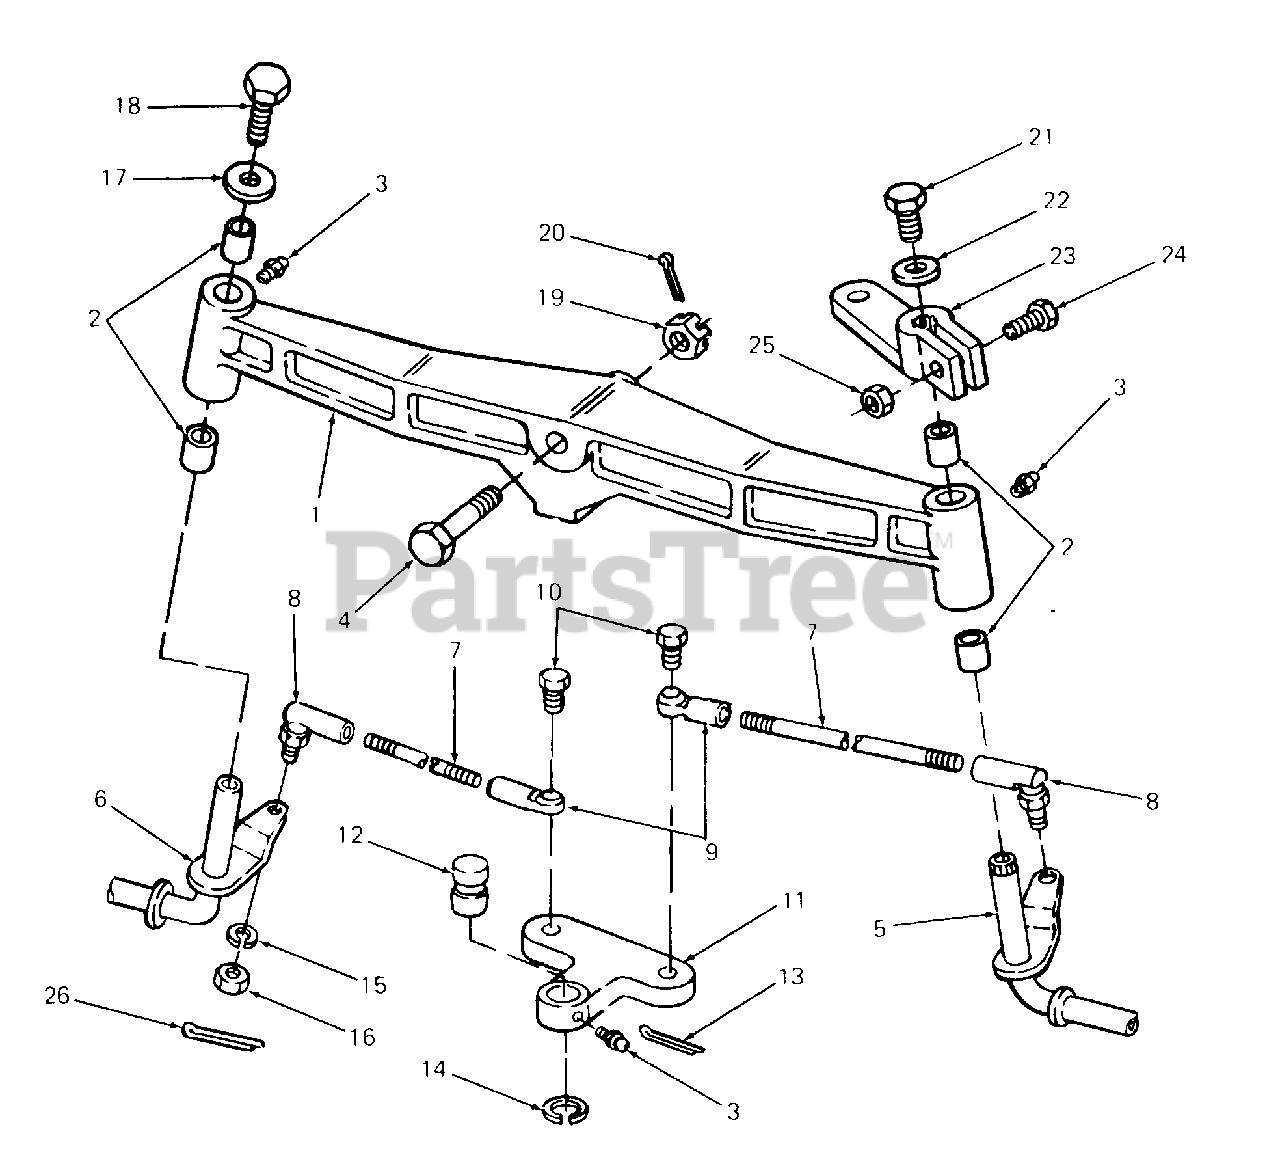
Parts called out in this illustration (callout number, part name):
1	Axle Assy, Front
3	Fitting, Lube, 3/16 Drive
4	Bolt, Hex, 3/4-10 X 5.0 Lg GR5 w/Hole
8	Ball Joint, 1/2-20
9	Alignabal End
10	Screw, Hex Cap, 3/8-16 X 1.5 Lg GR5 w/Hole
11	Steering Lever w/Fitting
12	Pin, Steering Pivot
13	Pin, Cotter, 3/32 Dia X 1.0 Lg
14	Ring, Retaining
15	Washer, Lock, 1/2 Dia
16	Nut, Hex Castle, 1/2-20 GR5
17	Washer, Flat, .531 X 1.75 X .090 Thk
18	Screw, Hex Cap, 1/2-13 X .75 Lg GR5
19	Nut, Hex Castle, 3/4-10
20	Pin, Cotter, 1/8 X 1.5 Lg
21	Screw, Hex Cap, 3/8-24 X 1.00 Lg GR5
22	Washer, Flat, .406 X 1.5 X .112 Thk
23	Arm, Steering
24	Screw, Hex Cap, 5/16-18 X 1.38 Lg GR5
25	Nut, Hex Center Lock, 5/16-18 GR5
26	Pin, Cotter, 3/32 Dia X 1.25 Lg
